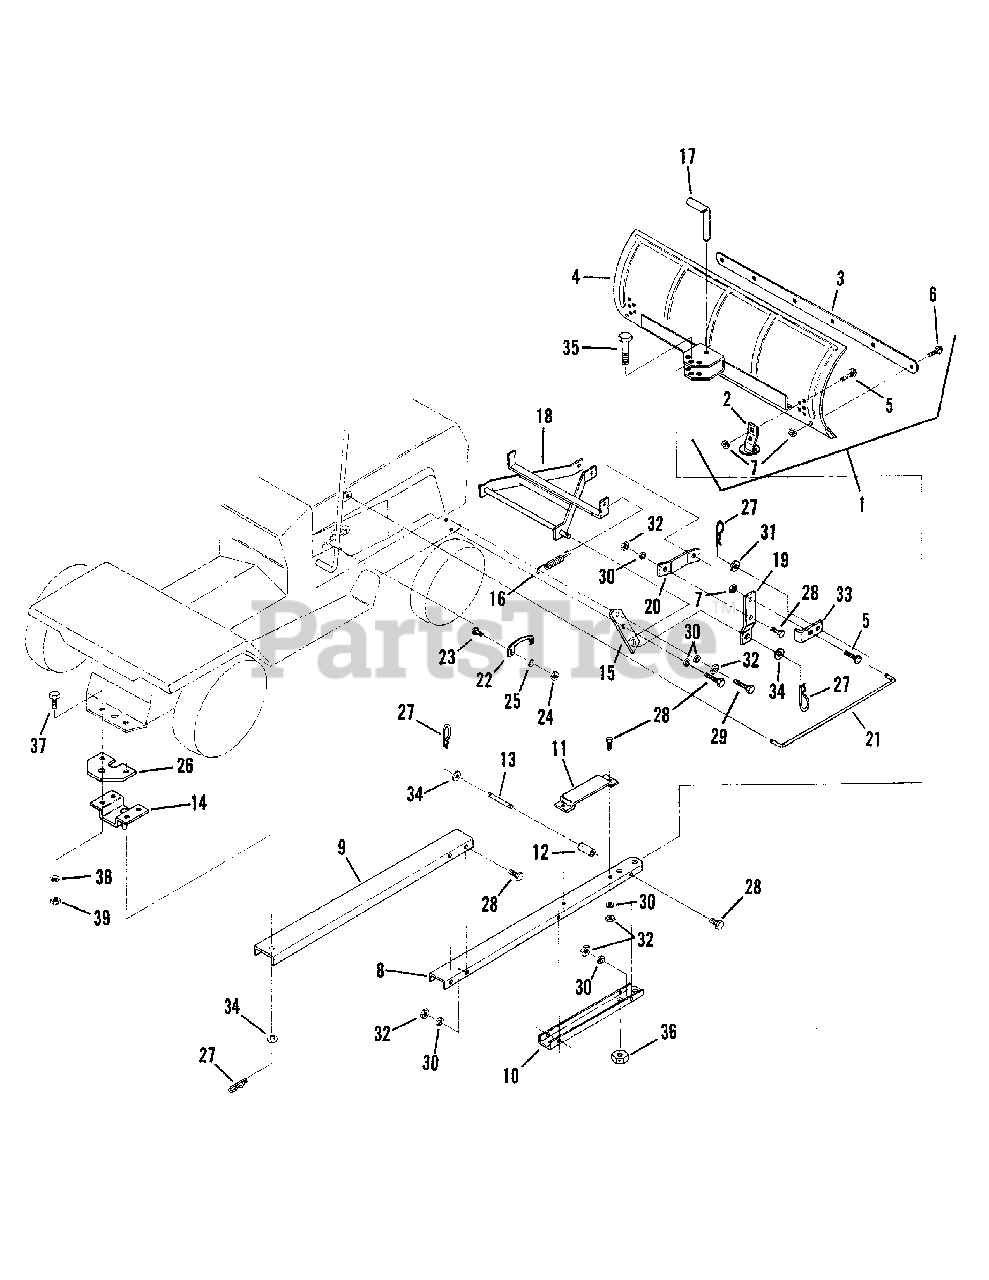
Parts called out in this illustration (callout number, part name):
1	ASSEMBLY, Blade 42" (Includes items 2 thru 7)
2	SLIDE STRUCTURE
3	SCRAPER
5	CARRIAGE BOLT, 3/8Cx1" Round Head
6	CARRIAGE BOLT 3/8Cx3/4 Short Neck
7	NUT, 3/8·16 Hex Center Lock
8	BEAM, Front
9	BEAM, Rear
10	PLATE, Front Hitch
11	BRACKET, Lift
12	ROLLER, Lift
13	PIN, Lift Roller
14	HITCH, Rear Yoke
15	PLATE, Side Support
16	SPRING, Lift Assist
17	PIN, Latch
18	STRUCTURE, Lift Yoke
19	ARM,Lift
21	ROD, Operating
22	PLATE, Quadrant Lockout
23	CARRIAGE BOLT, 1/4Cx5/8 Flat Head
24	NUT, 1/4C Hex
25	LOCKWASHER, 1/4 Internal Tooth
26	DRAWBAR, Short Aux.
27	PIN, Hair Cotter
28	SCREW, 3/8Cx1 Hex Head Cap
29	SCREW, 3/8Cx1 1/2 Hex Head Cap
30	WASHER 3/8 Split Lock
31	WASHER,3/8 Flat
32	NUT, 3/8C Hex
33	CLIP
34	WASHER, 1/2 Flat
35	SCREW, 1/2Fx2 3/4 Hex Head Cap
36	NUT, 1I2F Hex Lock
37	SCREW, 5/16Cx1" Hex Head Cap
38	WASHER, 5/16 Split Lock
39	PIN, Hair
40	TAB, Lift Lever
